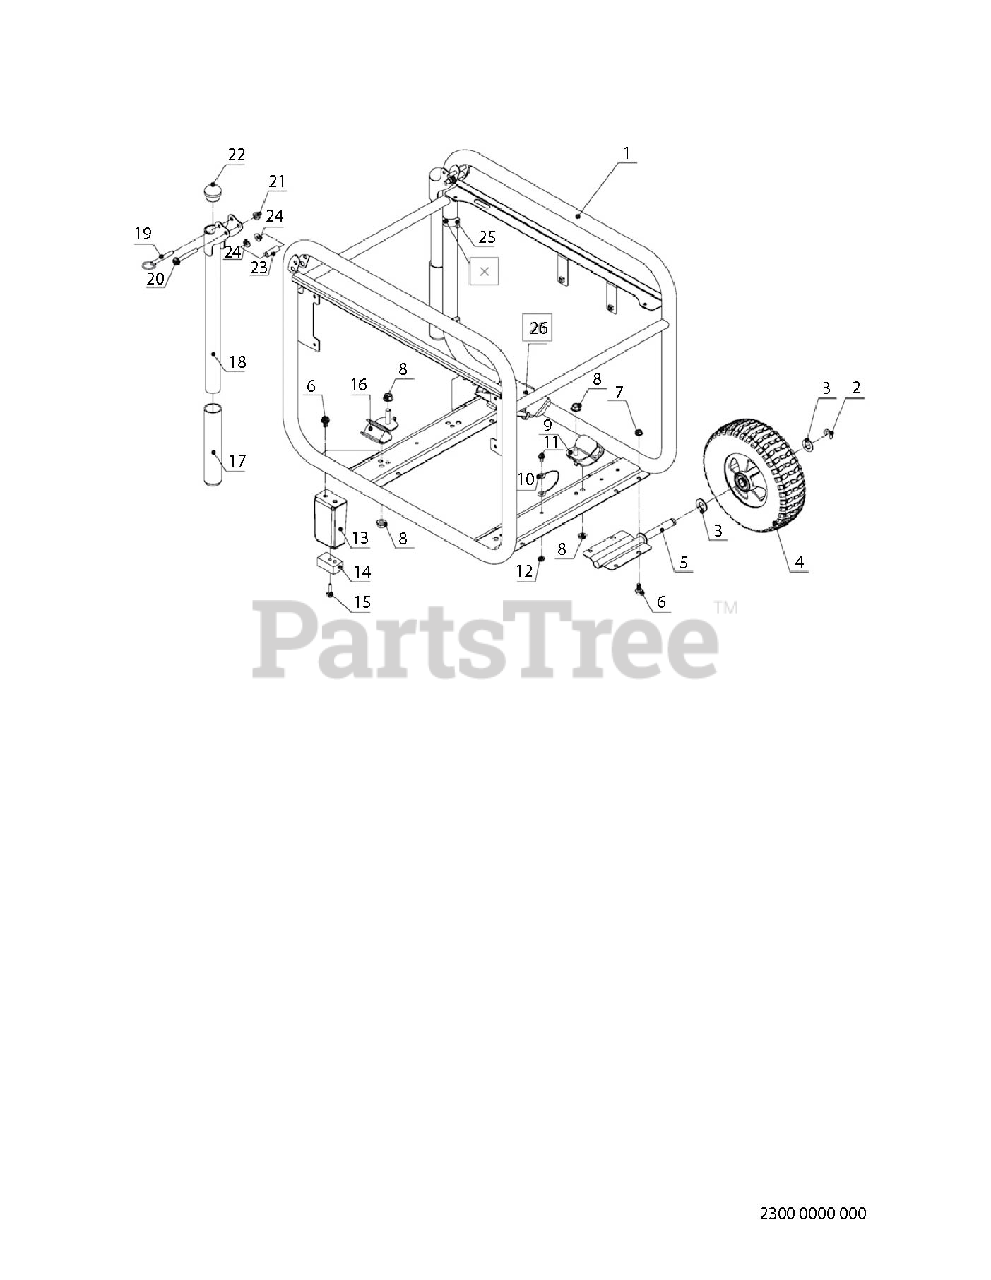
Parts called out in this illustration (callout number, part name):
1	FRAME
6	BOLT
7	NUT FLANGE
8	HEXAGON NUT
9	MOUNT
10	EARTH WIRE
11	BOLT
12	FLANGE NUT
15	FLANGE BOLT
20	HEXAGON FLANGE BOLT
